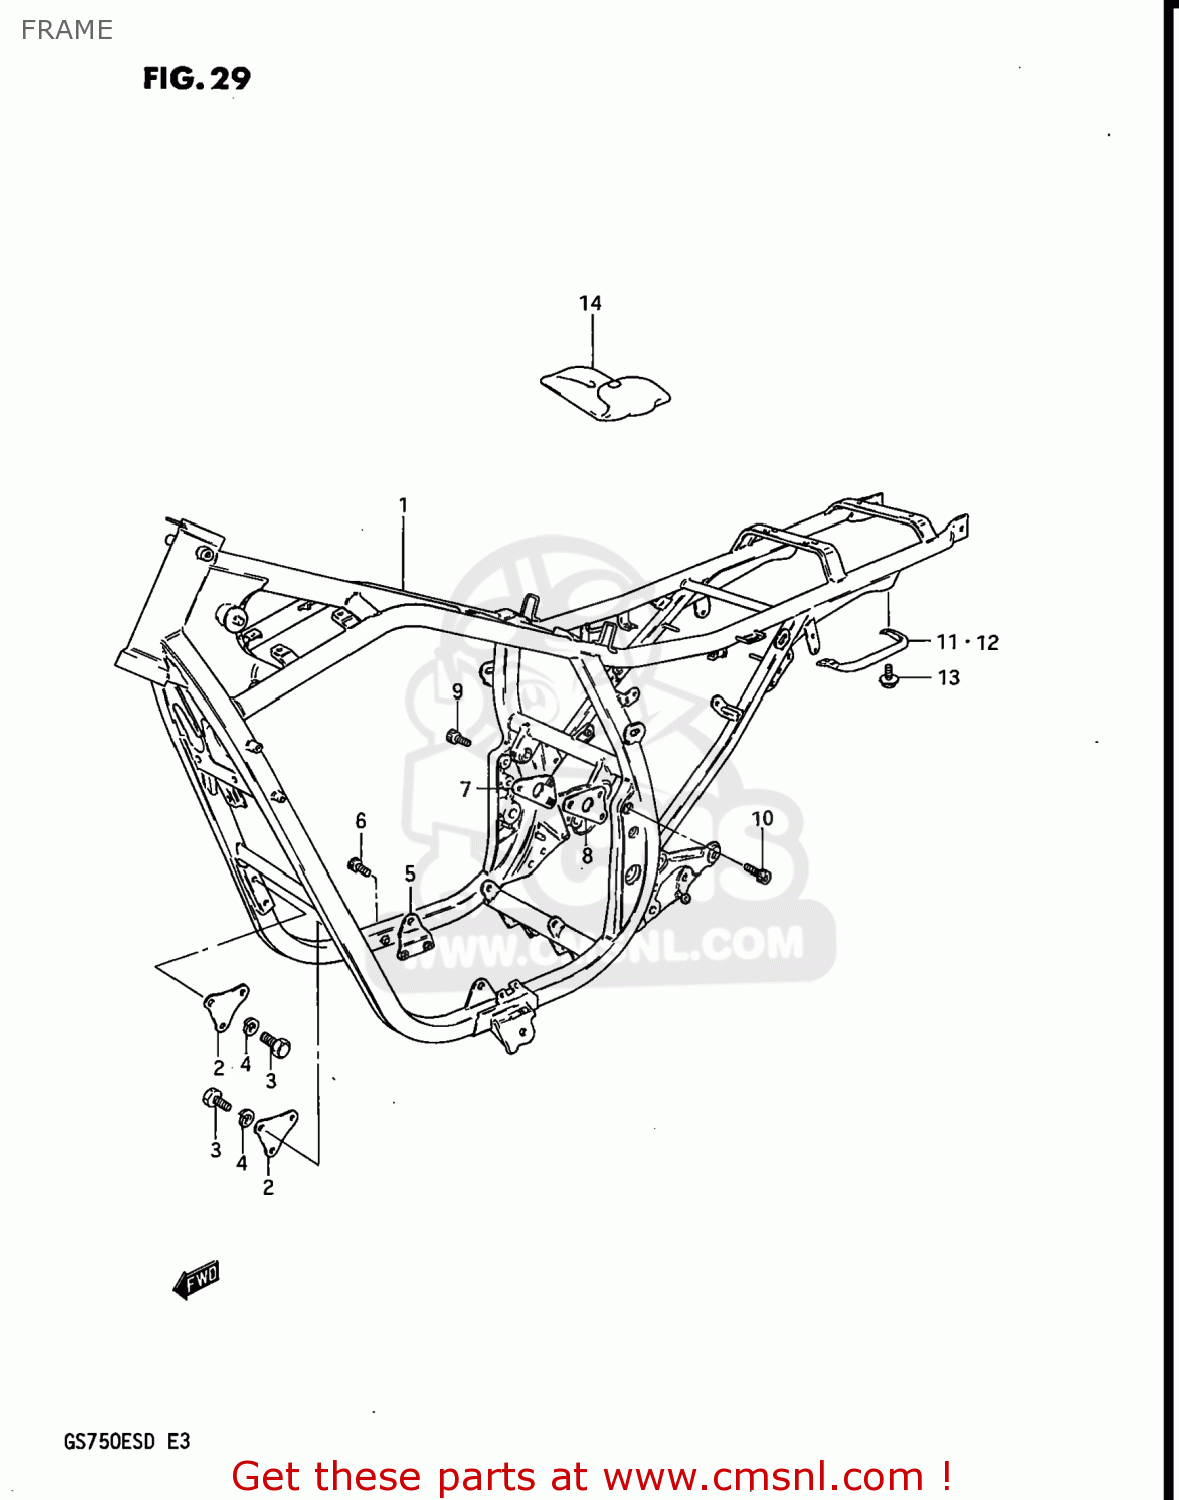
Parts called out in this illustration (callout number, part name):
1	FRAME
2	PLATE,ENGINE MOUNTING NO
3	BOLT
4	LOCK WASHER
5	PLATE,ENGINE MOUNTING NO
6	BOLT
7	PLATE,ENGINE MOUNTING NO
8	PLATE,ENGINE MOUNTING NO
9	BOLT
10	BOLT
11	GRIP,FRAME HANDLE
12	GRIP,FRAME HANDLE,LEFT
13	BOLT, LOWER
14	TOOL SET
15	HOLDER,TOOL
